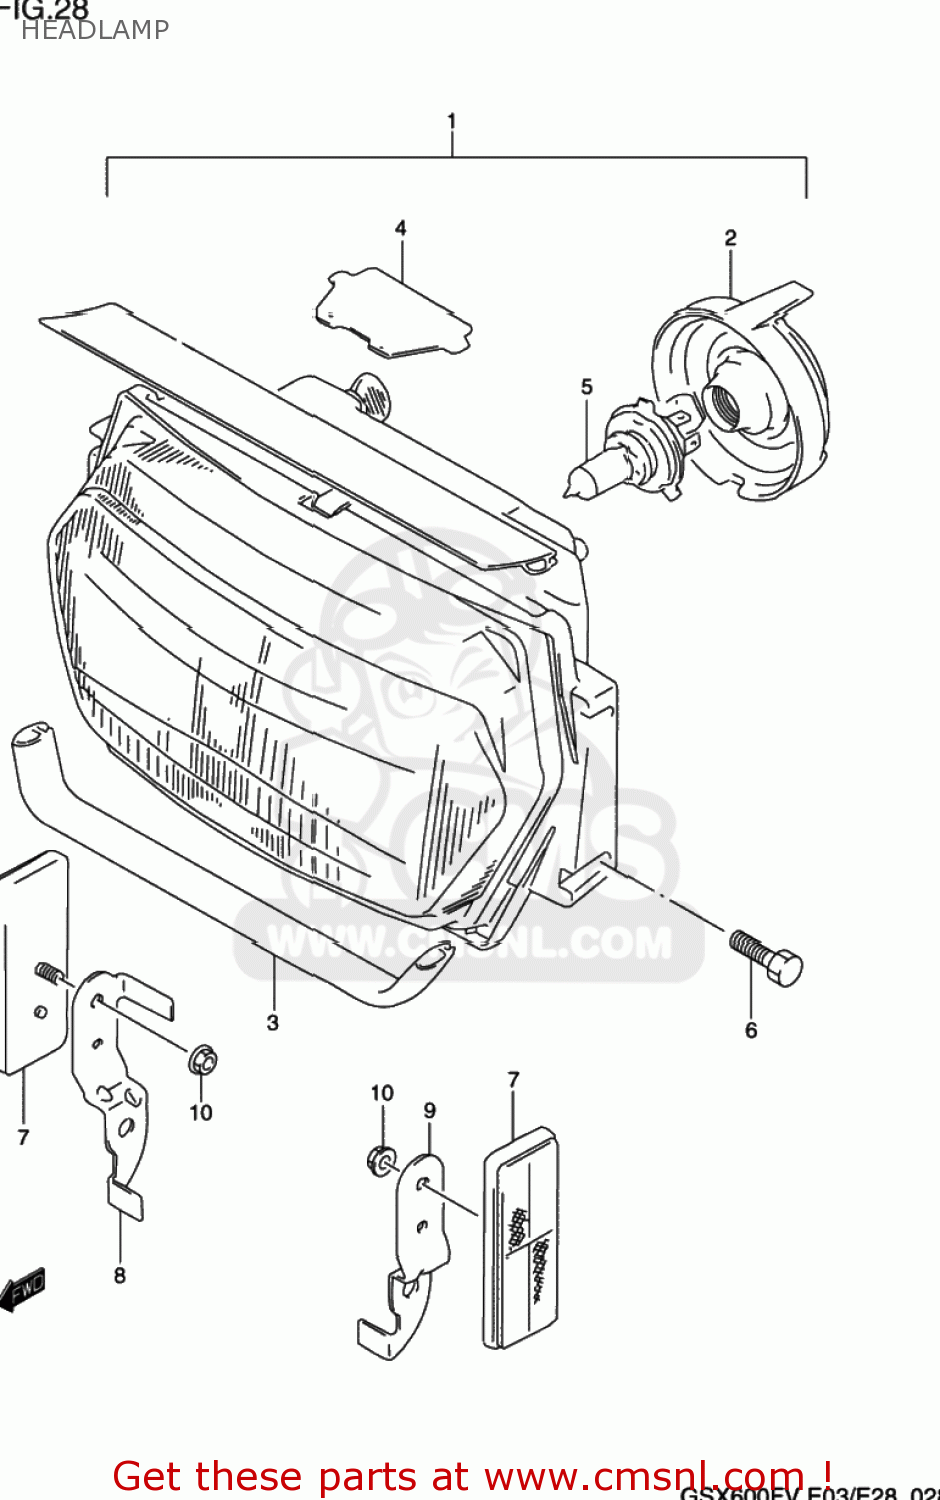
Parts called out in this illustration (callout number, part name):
1	HEADLAMP ASSY
2	COVER,SOCKET
3	GASKET,HEADLAMP (NAS)
4	GASKET (NAS)
5	BULB(12V60/55W,H4)
6	BOLT, REAR
7	REFLEX REFLECTOR,FR SIDE
8	BRACKET,FR SIDE RR,R
9	BRACKET,FR SIDE RR,L
10	NUT
